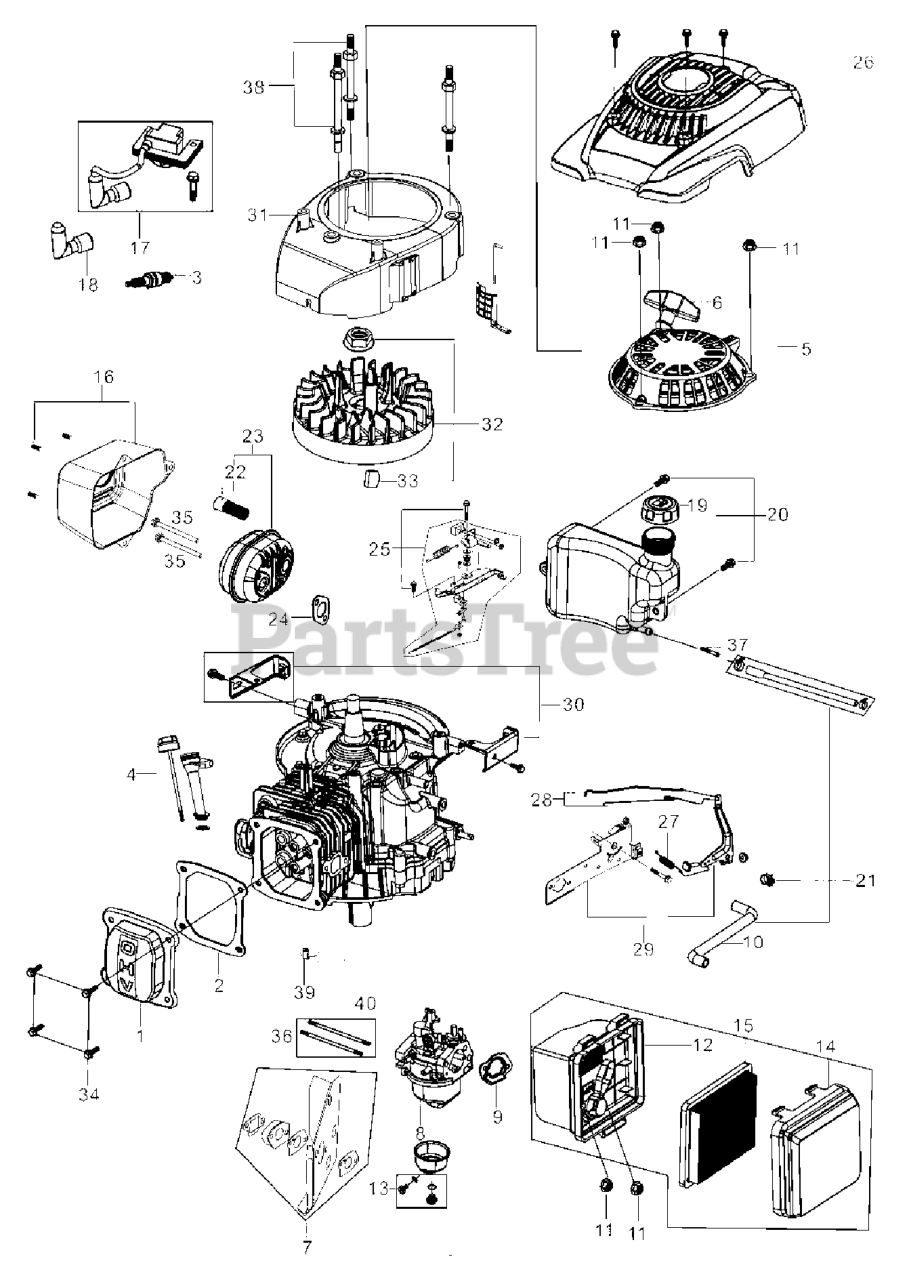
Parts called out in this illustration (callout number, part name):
1	COVER.SUBASSEMBLY.CYL.HEAD
2	GASKET.CYLIDER.HEAD.COVER
3	SPARK PLUG RATO.30010-Z030310-
4	DIPSTICK.OIL.RATO.
5	STARTER RECOIL W/HARDWAR.RATO.
6	STARTER HANDLE RECOIL.RATO.282
7	GASKET KIT CARBURETTOR.RATO.R1
8	CARB.ASM.16100-Z341010-0099.RA
9	GASKET AIR CLEANER.RATO.17001-
10	TUBE BREATHER.RATO.17004-Z0303
11	NUT FOR AIR CLEANER.INSTAL.
12	AIR CLEANER BASE.RATO.17101-Z0
13	CARBURETTOR KIT RATO.R170
14	COVER AIR CLEANER.RATO.17104-Z
15	AIR.FILTER.RATO
16	MUFFLER GUARD W/HARDWARE.RATO.
17	IGNITION COIL ASSY RATO,R170
18	CAP.SPARK.PLUG.RATO
19	COVER.FUEL.TANK
20	FUEL.TANK ASSY.W/HARDWARE
21	HOSE KIT KIT.FUEL,BREATHER.W.C
22	GUARD.MUFFLER.ASM.RATO.RV170
23	MUFFLER RATO.18100-Z340210-QA0
24	GASKET EXHAUST.RATO.18001-Z340
25	BRAKE ASSY RATO.R170
26	SHROUD.ENG.RATO.MCCUL.140/170
26A	SHROUD.MCCULLOCH.RATO.RV140
27	SPRING GOVERNOR.RATO.16063-Z34
28	LINKAGE THROTTLE.ASM.RATO.R170
29	THROTTLE CONTROL ASM.RATO.R170
30	FUEL TANK.ASSY.BRKTS.LF&RT
31	BLOWER HOUSING RATO.28110-Z250
32	FLYWHEEL ASSY W/HARDWARE.RATO.
33	KEY CRANKSHAFT RATO 90524-Z030
34	BOLT VALVE COVER RATO 90007-06
35	STUD M6*95 RATO 250310-0000
36	STUD M6*95.RATO.90204-Z030110-
37	FUEL FILTER RATO 16652-Z030110
38	STUD BLOWER HOUSING RATO 28191
39	SENSOR.THERMAL.CHOKE.RATO
40	ROD.CONNECTING.THERMAL.CHOKE.R
